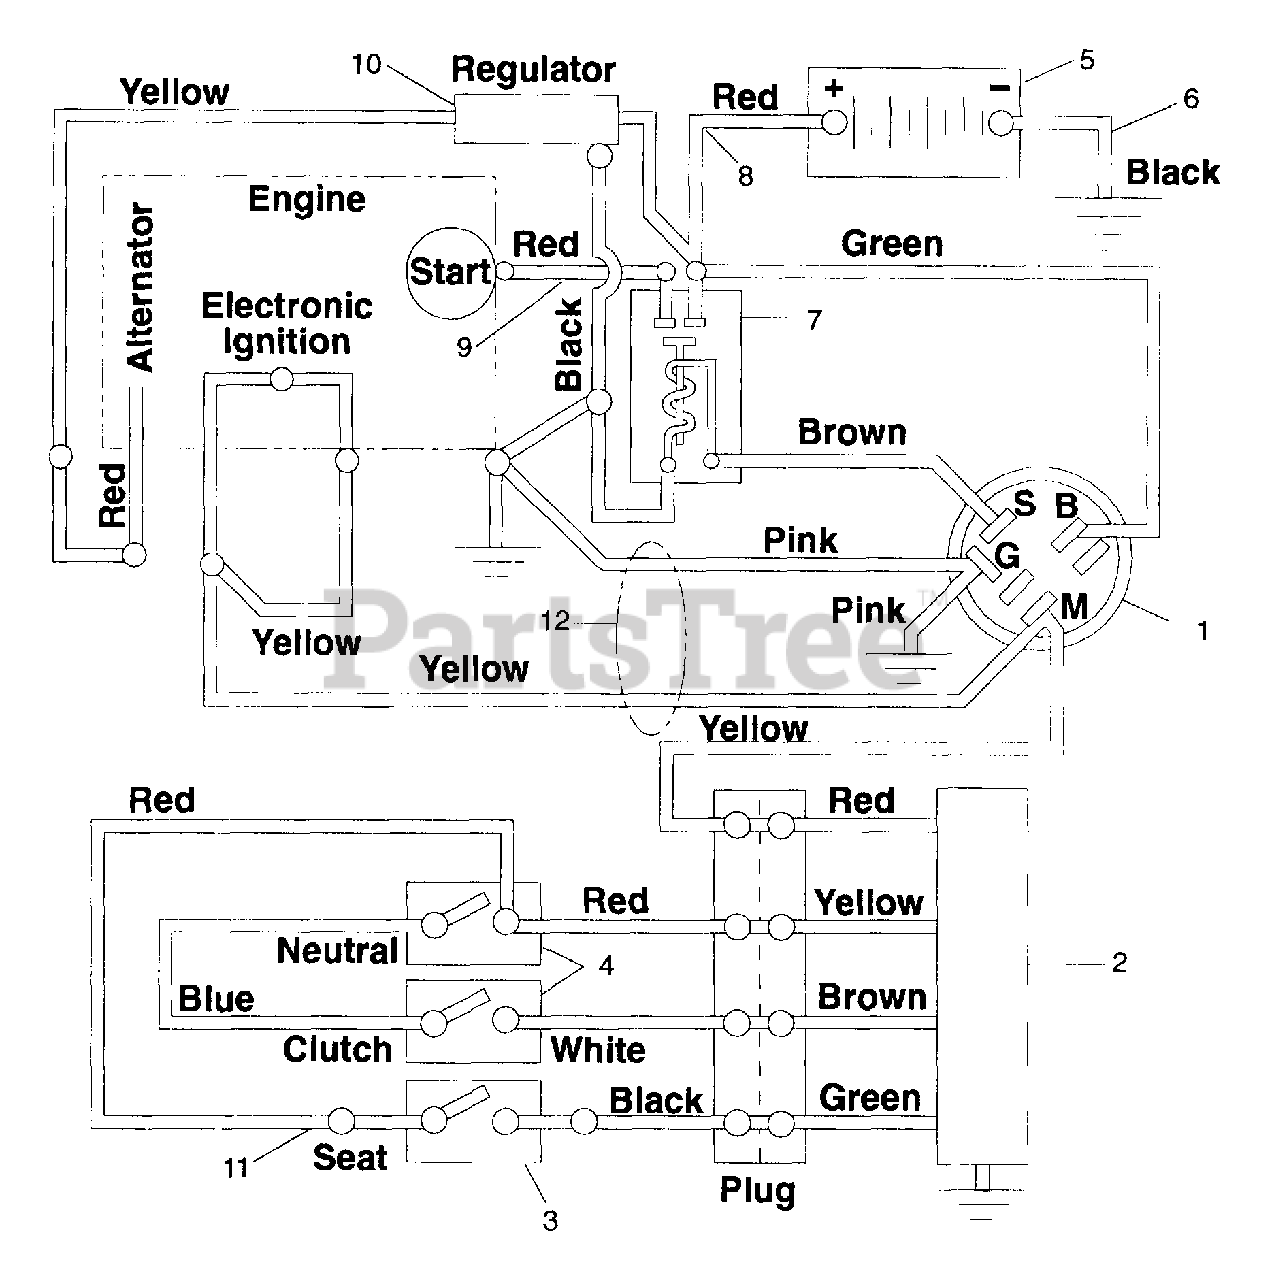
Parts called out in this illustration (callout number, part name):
1	SWITCH ASSEMBLY
2	MODULE
3	SWITCH SEAT
4	SWITCH INTERLOCK
4	SWITCH- SNAP MTG N.O.
5	BATTERY
6	GROUND CABLE .25X13.00X.31
7	SOLENOID
8	STARTER CABLE 16"
9	STARTER CABLE 13"
10	REGULATOR
11	ADAPTER - SEAT SWITCH
12	WIRE HARNESS RM B&S ENGINES
